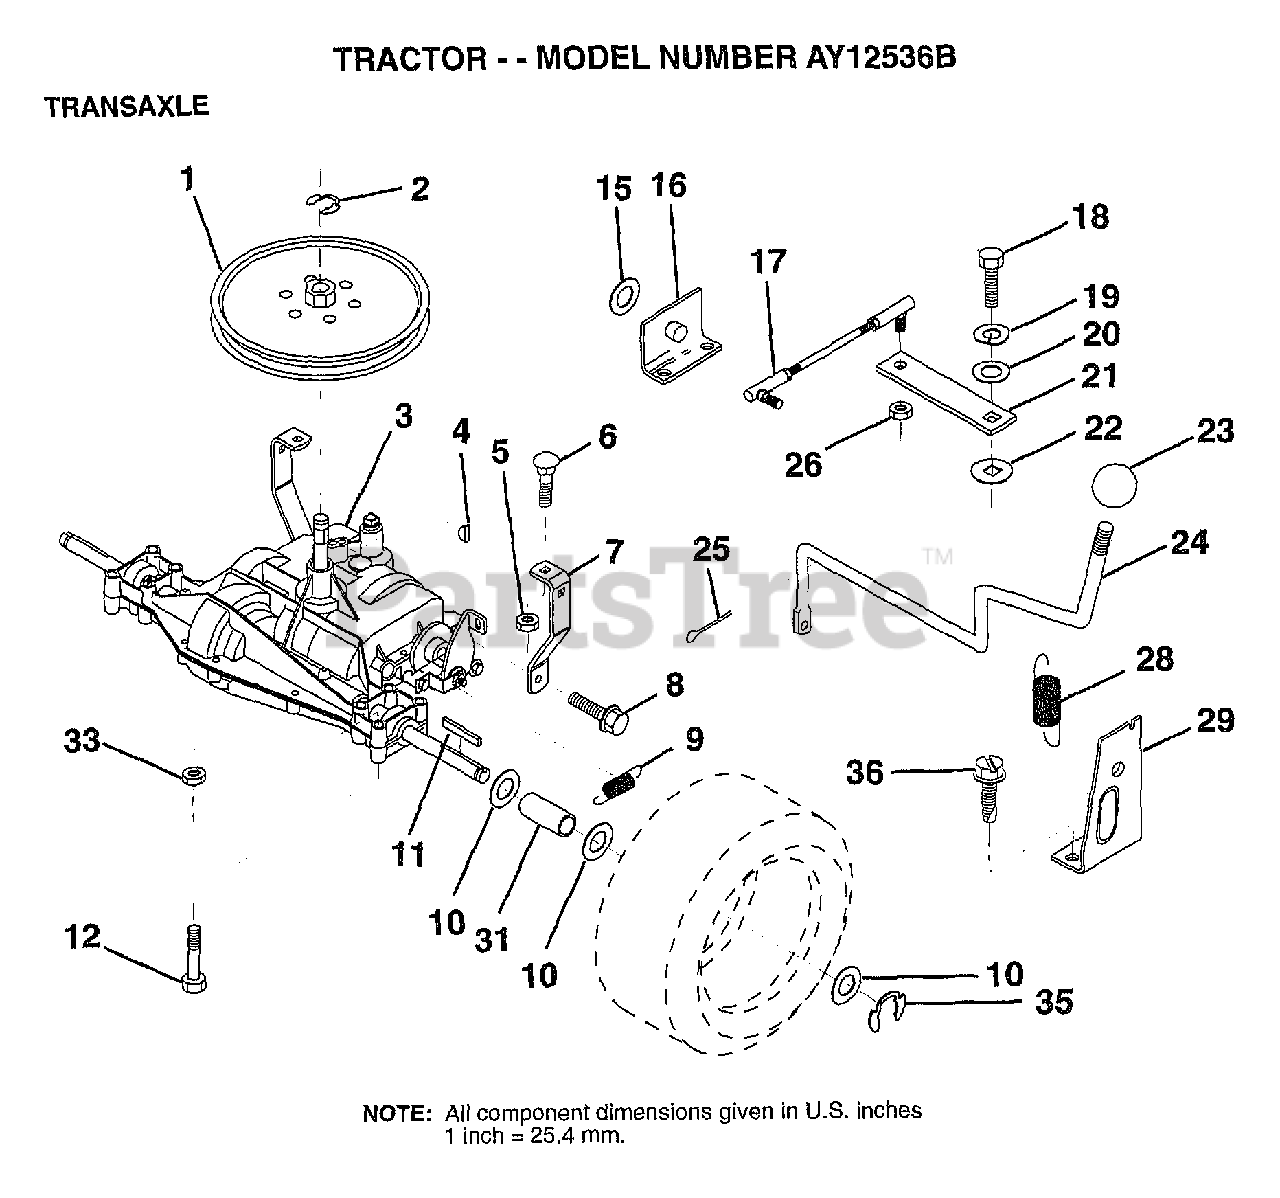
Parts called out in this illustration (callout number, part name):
1	PULLEY
6	BOLT
7	"STRAP,TORQUE"
8	SCREW
9	SPRING.BRAKE.RETU
10	WASHER
11	SQUARE KEY
12	BOLT
16	"SUPT,HDLE SHT LH"
17	"LINK,SHIFT"
18	BOLT.1/4-28.W/PAT
19	LOCKWASHER
20	WASHER LT
21	ARM SHIFT
22	WASH-SHFT PLT LT
23	KNOB T (1/2-HOLE)
24	"ROD,SHIFT"
25	PIN COTTER 1/8
26	NUT.LOCK.5/16-24
28	"SPRING,EXT"
29	"SUPT,HDLE RH"
31	SPACER LT
35	E-RING LT
36	SCREW
